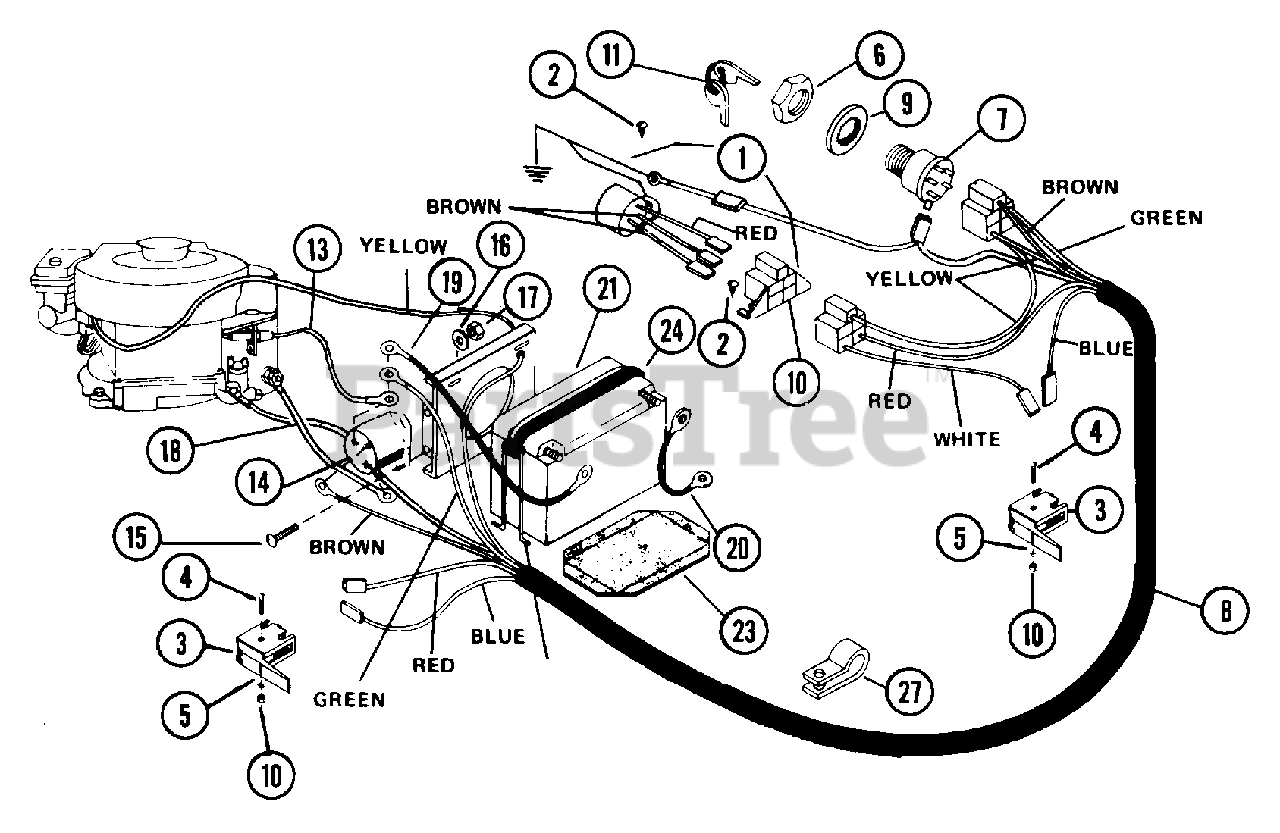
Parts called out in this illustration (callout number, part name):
1	MODULE T KIT
1	MODULE B KIT
2	SCR-TAP 10-12X.50 CRPH PL A
3	SWITCH INTERLOCK
4	SCR-MCH 10-24X1.00 SLRH PL
5	WSHR-LK 10X.047 MED PL
6	NUT .625-32 ALUM
7	IGNITION SWITCH ASSEMBLY
8	WIRE HARNESS
8	WSHR-LK-INT .625X.045 PL
9	NUT-HEX 10-24 PL
10	CONNECTOR
11	KEYS
13	CHARGING WIRE
14	SOLENOID,STARTER SWITCH
15	BLT-RDHDSQNK .25-20X.50 SHT PL
16	WSHR-LK .250X.077 HVY PL
17	NUT-HEX .250-20 PL
18	GROUND CABLE .25X13.00X.31
19	GROUND CABLE .25X13.00X.31
20	GROUND CABLE .25X13.00X.31
20	GROUND CABLE
21	BATTERY
22	BATTERY TRAY
23	RUBBER PAD
24	BATTERY STRAP
25	HOOK
26	SCR-TAP .312-18X.50 HWH PL TR
